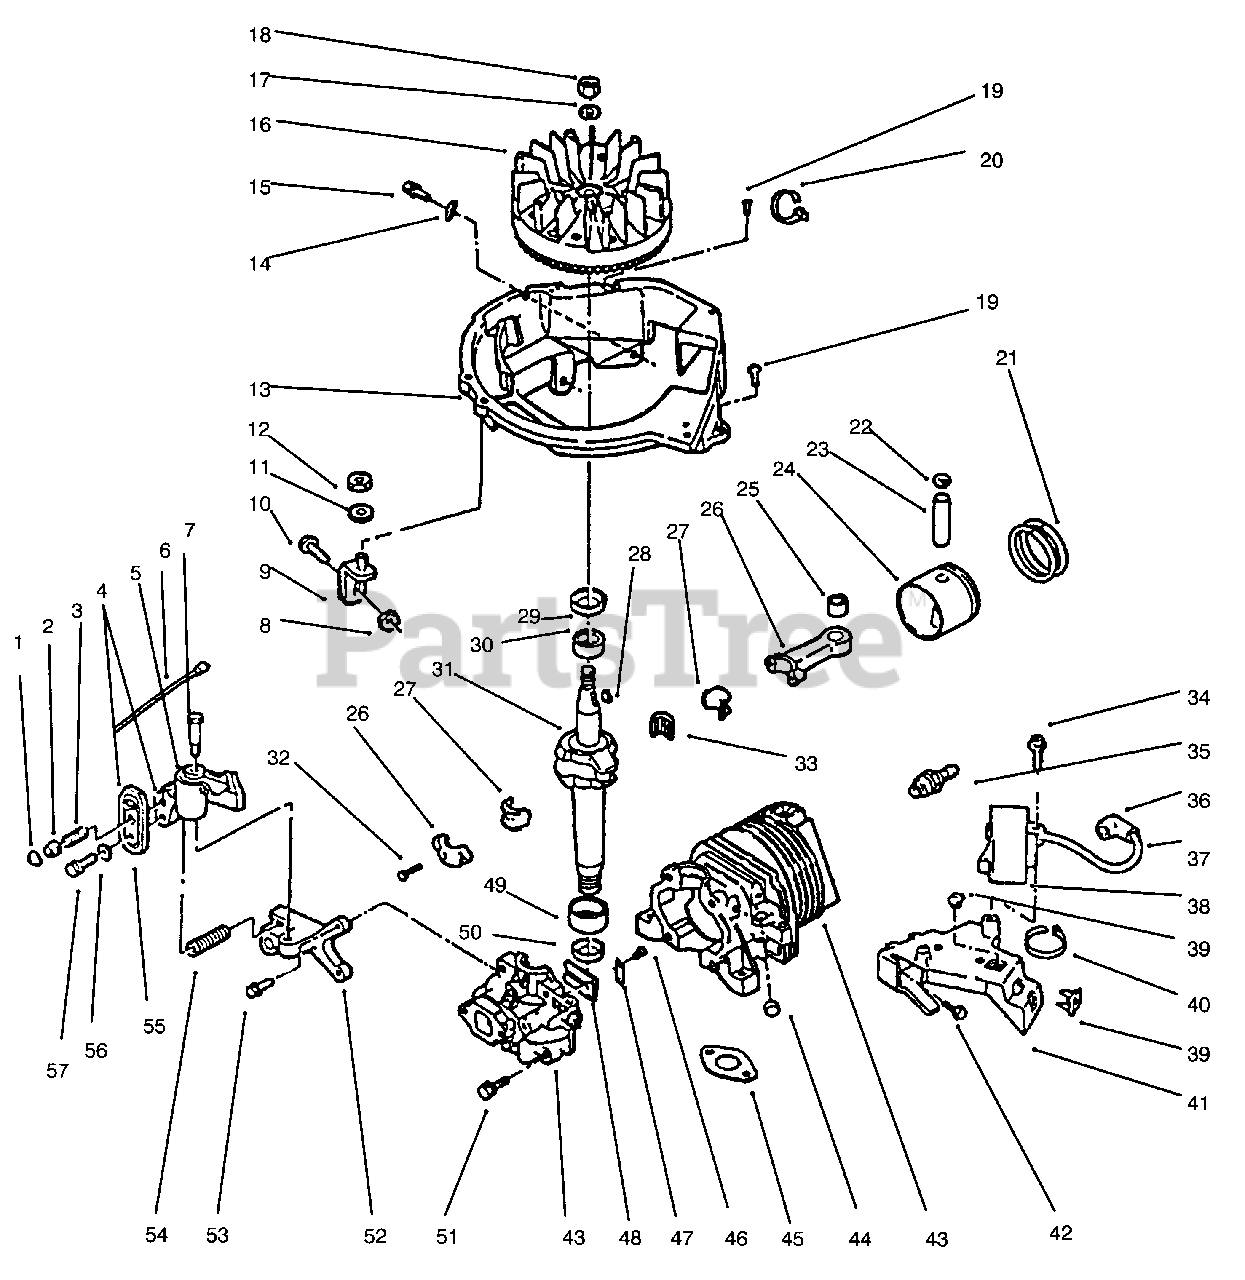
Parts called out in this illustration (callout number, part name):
1	Retainer
2	Actuator-Brake Lever
3	Spring-Cable, Return
4	Assembly-Switch (Incl. Ref. #1, 6, 20, & 56-58)
5	Assembly-Brake
6	Wire Lead
7	Bolt-Shoulder
9	Assembly-Brace
11	Washer
13	Shroud-Base
14	Clip-"J"
16	Assembly-Flywheel
17	Washer-Lock
18	Nut-Flywheel
20	Tie Strap
21	Set-Ring
22	Ring-Retaining
23	Pin-Wrist
24	Assy.-Piston & Conn. Rod (Incl. Ref. #24-27, & 32-33)
25	Assembly-Bearing
26	Assembly-Connecting Rod (Incl. Ref. #25-27 & 32-33)
27	Liner-Split
28	Key-Flywheel
29	Seal-Oil
30	Bearing-Main
31	Crankshaft
33	Set-Needle Bearing
34	Screw
35	Spark Plug
36	Cover-Terminal
37	Wire Lead
38	C.D. Ignition Module (Incl. Ref. #36-37 & below listed item.)
39	Grommet
40	Tie Strap
41	Bracket-C.D.
43	Assy.-Cyl./Crankcase Cov. (Incl. Ref. # 46-48, 51, 53 & below listed item.)
45	Gasket-Exhaust
47	Plate-Reed
49	Bearing-Main
50	Seal-Oil
52	Bracket-Brake
54	Spring-Brake
55	Assembly-Case
56	Washer
57	Screw
